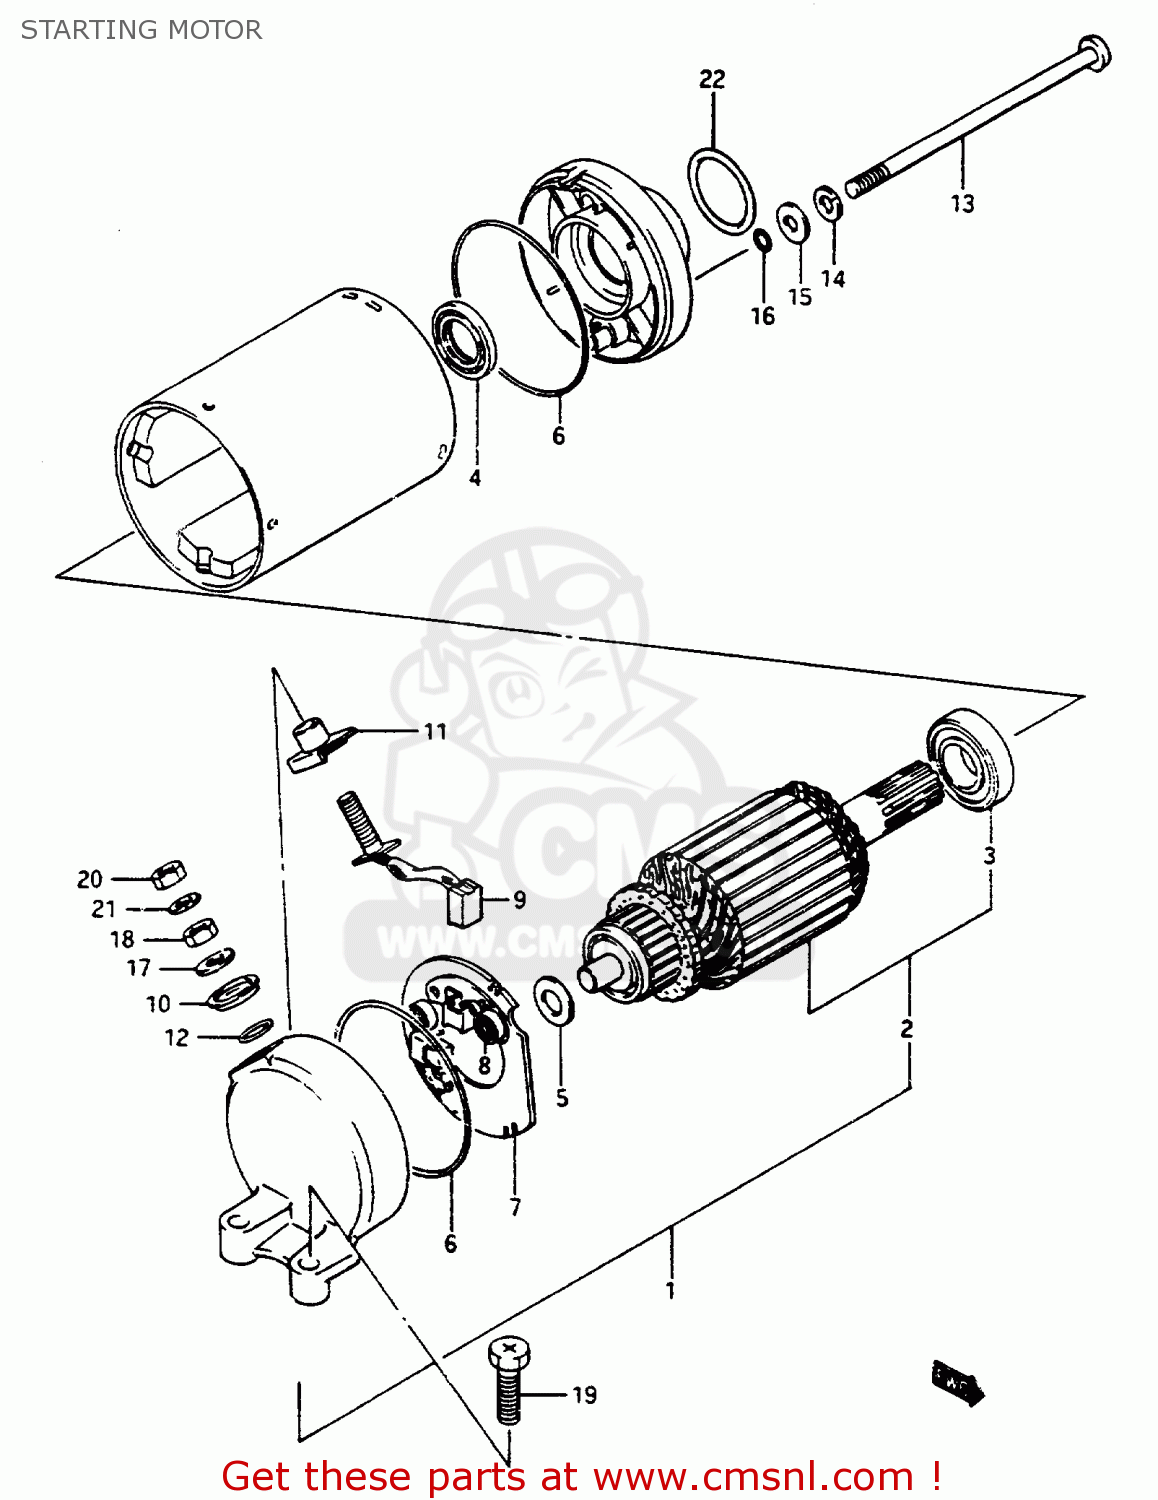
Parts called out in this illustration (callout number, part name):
1	MOTOR ASSEMBLY,STARTING
2	ARMATURE
3	BEARING
4	SEAL,OIL
5	SHIM,ARMATURE
6	O RING
7	HOLDER,BRUSH
8	SPRING
9	BRUSH SUB ASSY,STARTING MOTOR
10	BUSHING
11	BUSH,B
12	O RING
13	BOLT
14	LOCK WASHER
15	WASHER
16	O RING
17	WASHER
18	NUT 6MM
19	SCREW (6X25)
20	NUT
21	WASHER,LOCK
22	O RING(D:3,ID:24.5)
